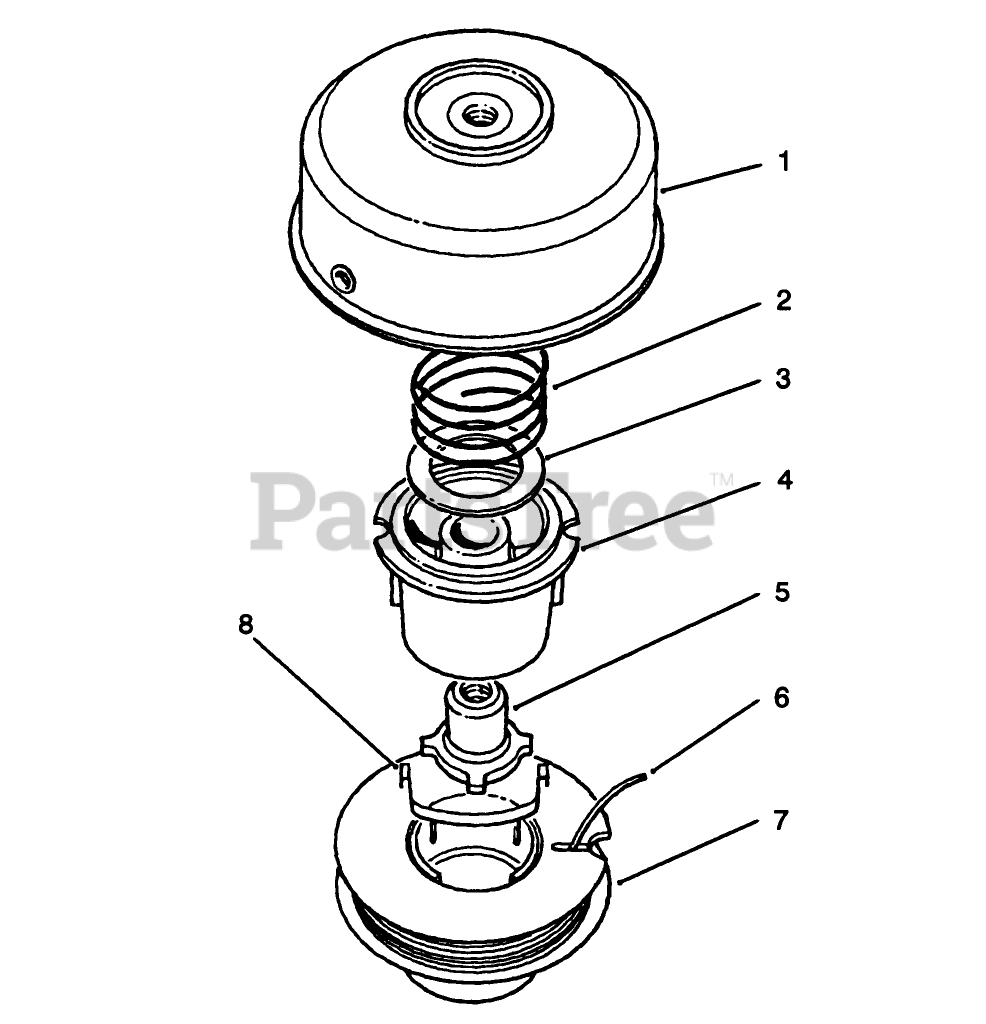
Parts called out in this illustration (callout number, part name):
1	DRUM EYELET ASM
2	SPRING
3	WASHER-FLAT
4	SPOOL CORE
5	LH DRIVER
6	Line-Cutting .095 Dia.
7	Spool Prewound .095 Dia. 30- (Incl. Ref. #6 & 8)
8	SADDLE-SPOOL CAP
